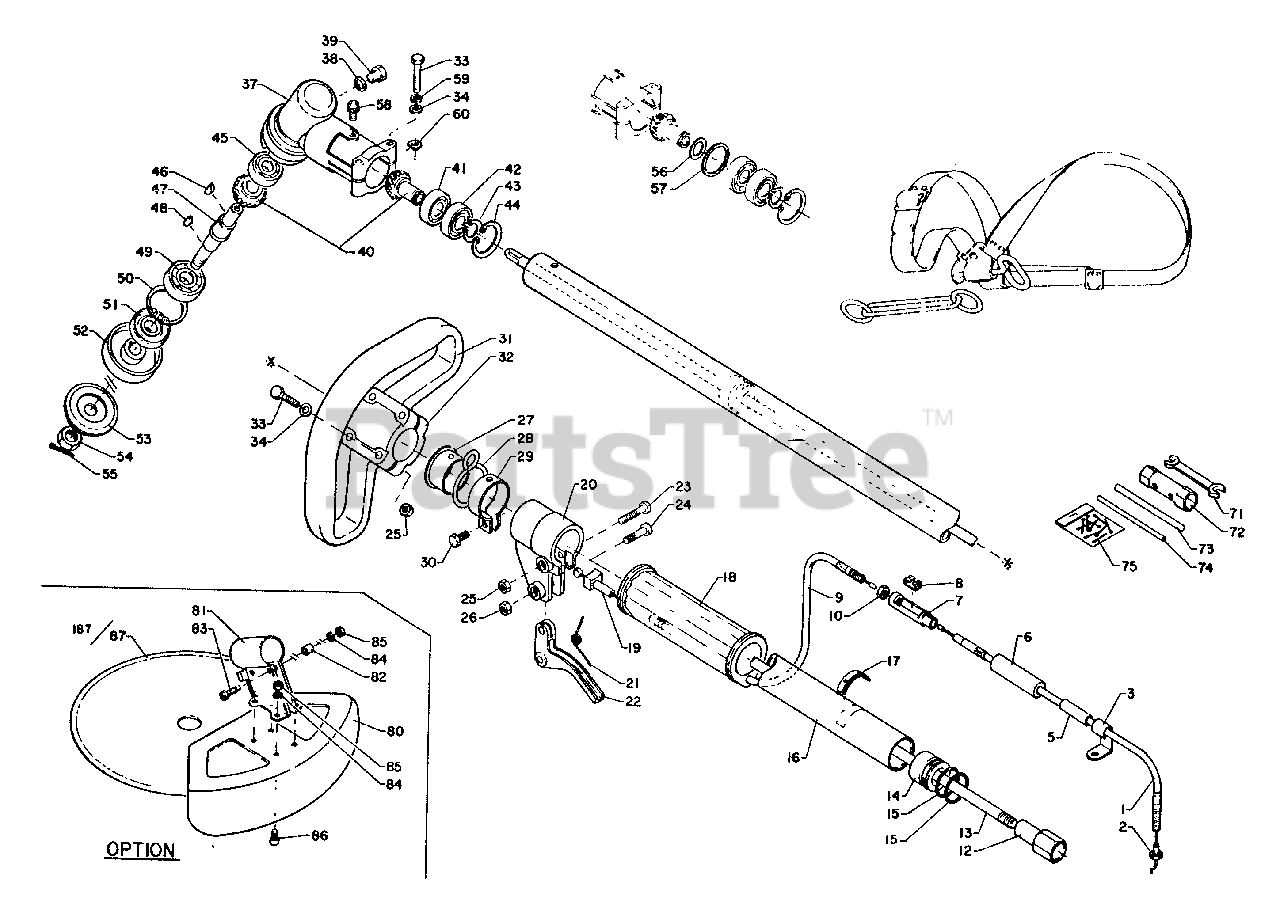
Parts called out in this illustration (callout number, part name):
1	CABLE, THROTTLE
3	CLAMP
5	TUBE, VINYL
6	SLEEVE, JOINT RETAINER
7	CONNECTOR
9	CABLE, THROTTLE
13	DRIVESHAFT
14	STOPPER
15	O-RING 22
16	MAIN PIPE ASSY
17	LABEL - ALIGNMENT
18	GRIP
19	GUIDE, CABLE
20	BRACKET, TRIGGER
21	SPRING, THROTTLE
22	TRIGGER, THROTTLE
23	SCREW 5×28
25	NUT M5
26	LOCKNUT - 5
27	COLLAR
28	HOOK, SWIVEL
29	CLAMP
30	BOLT - 5×10
31	HANDLE
32	BRACKET, HANDLE
33	BOLT 5×30
34	WASHER, FLAT 5.5×10×0.8
37	HOUSING, GEAR CASE
38	GASKET
39	BOLT - 8×6
40	GEAR SET
41	BEARING, BALL 6001
42	BEARING, BALL 6001
43	RING, RETAINING - 12
44	RING, SNAP 28
45	BEARING, BALL 6000
47	DRIVESHAFT
49	BEARING, BALL - 6201 C3
50	RING, SNAP Ø32
51	SEAL, OIL
52	PLATE, ADAPTER - UPPER
53	PLATE, ADAPTOR - LOWER
55	PIN, COTTER 2×22
58	SCREW 5×10
59	WASHER, SPRING 5
71	SPANNER 8×10
72	WRENCH 17×19
73	ROD, HANDLE
74	TOOL, LOCKING 5×120 MM
75	PIN, COTTER 2×22 (PKG. OF 10)
80	GUARD
81	BRACKET
82	SPACER, GUARD
83	SCREW 5×18
84	WASHER, SPRING 5
85	NUT M5
86	SCREW 5×8
87	BLADE - 8 TOOTH -- 10"
187	SAW, CIRCULAR
